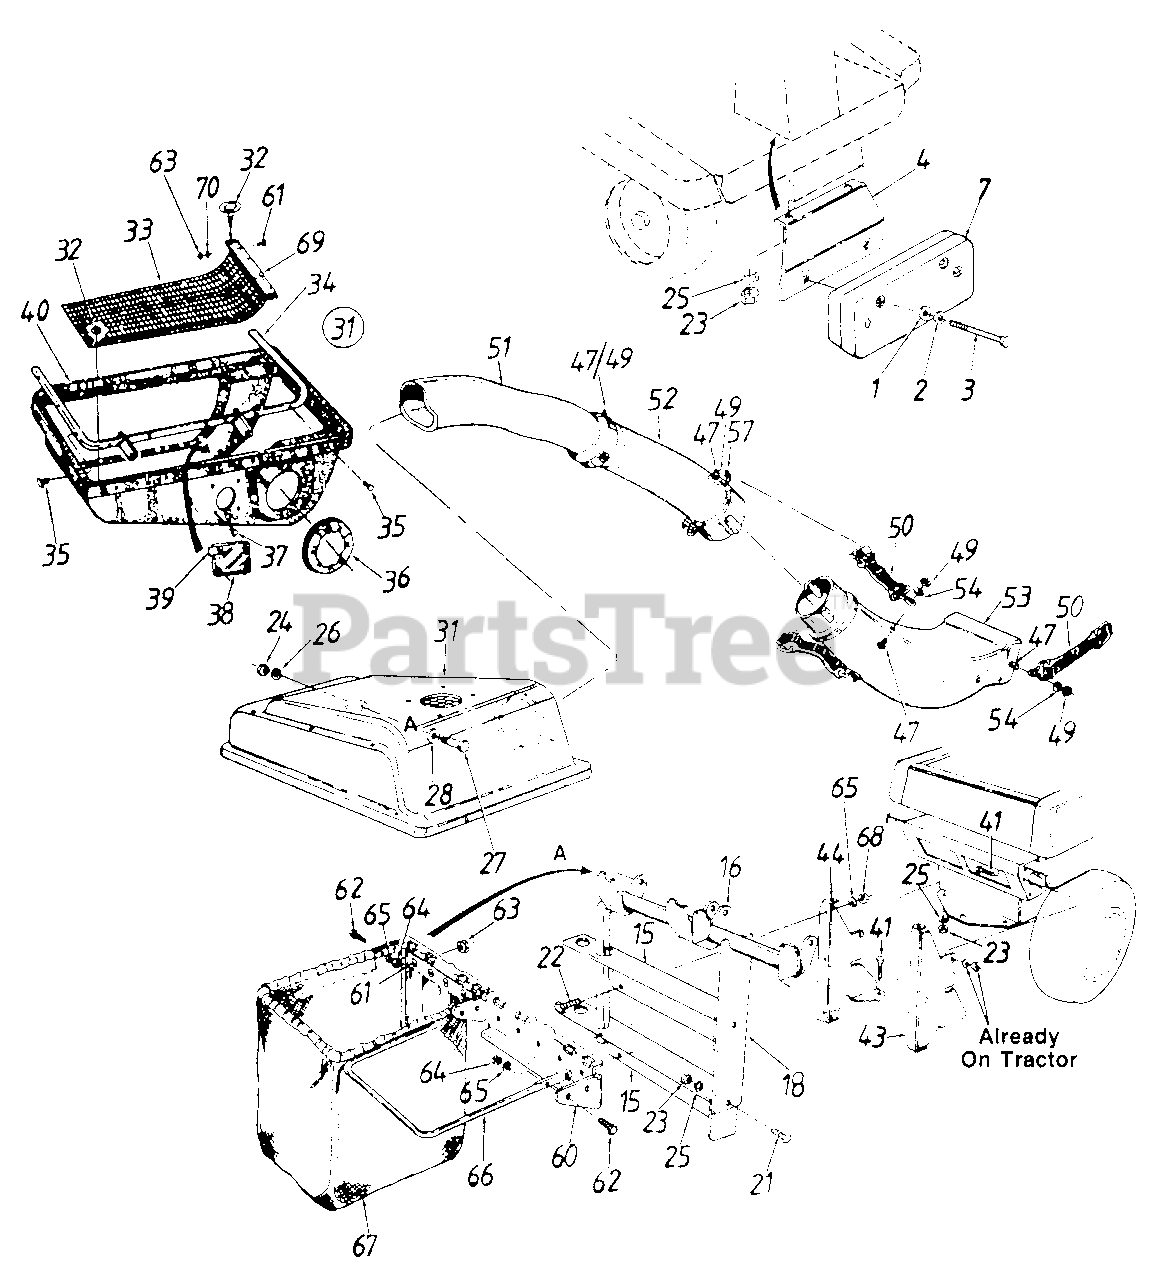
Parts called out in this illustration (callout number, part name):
1	Fl-Wash. .39" I.D. x 1.12" O.D.
2	Bell-Wash. .40" I.D. x .88" O.D.
3	Hex Bolt 3/8-16 x 4.5" Lg.
4	Counterweight Support Brkt.
7	Front Counterweight 38 lbs.
15	Support Tube Mtg. Brkt.
16	Support Tube Ass'y.
18	Catcher Latch and Support Brkt.
21	Hex Bolt 5/16-18 x .75" Lg.
22	Hex Bolt 1/4-20 x .62" Lg. Grade 5
23	Hex Nut 5/16-18 Thd.
24	Hex Nut 3/8-16 Thd.
25	L-Wash. 5/16" I.D.
26	L-Wash. 3/8" I.D.
27	Shld. Bolt 3/8-16 x .50" Dia.
28	Bell-Wash. .505" I.D. x 1.0" O.D.
31	Cover Ass'y.
32	Twist Fastener
33	Screen
35	Hex Tap Scr. 1/4" x .62" Lg.
36	Seal
37	Truss Mach. B-Tap Scr. #10 x .5" Lg.
38	Plastic Plate
39	Speed Nut
40	Grass Catcher Cover
41	Hex Bolt 5/16-18 x 1.0" Lg.
43	Support Brkt. R.H.
44	Support Brkt. L.H.
47	Hex Bolt 1/4-20 x .50" Lg.
49	Hex Ins. L-Nut 1/4-20 Thd
50	Retainer Strap Ass'y.
51	Catcher Elbow
52	Catcher Tube
53	Discharge Chute
54	L-Wash. .27" I.D. x .57" O.D.
57	Retainer Hook Brkt.
61	Truss Mach. Scr. #10-24 x .50" Lg.
62	Hex Bolt 1/4-28 x .75" Lg.
63	Hex Sems Nut #10-24 Thd.
64	Hex Nut 1/4-28 Thd.
65	L-Wash. 1/4" I.D.
67	Grass Catcher Bag
68	Hex Nut 1/4-20 Thd.
69	Screen Mtg. Brkt.
70	FI Wash. 1/4" I.D.
